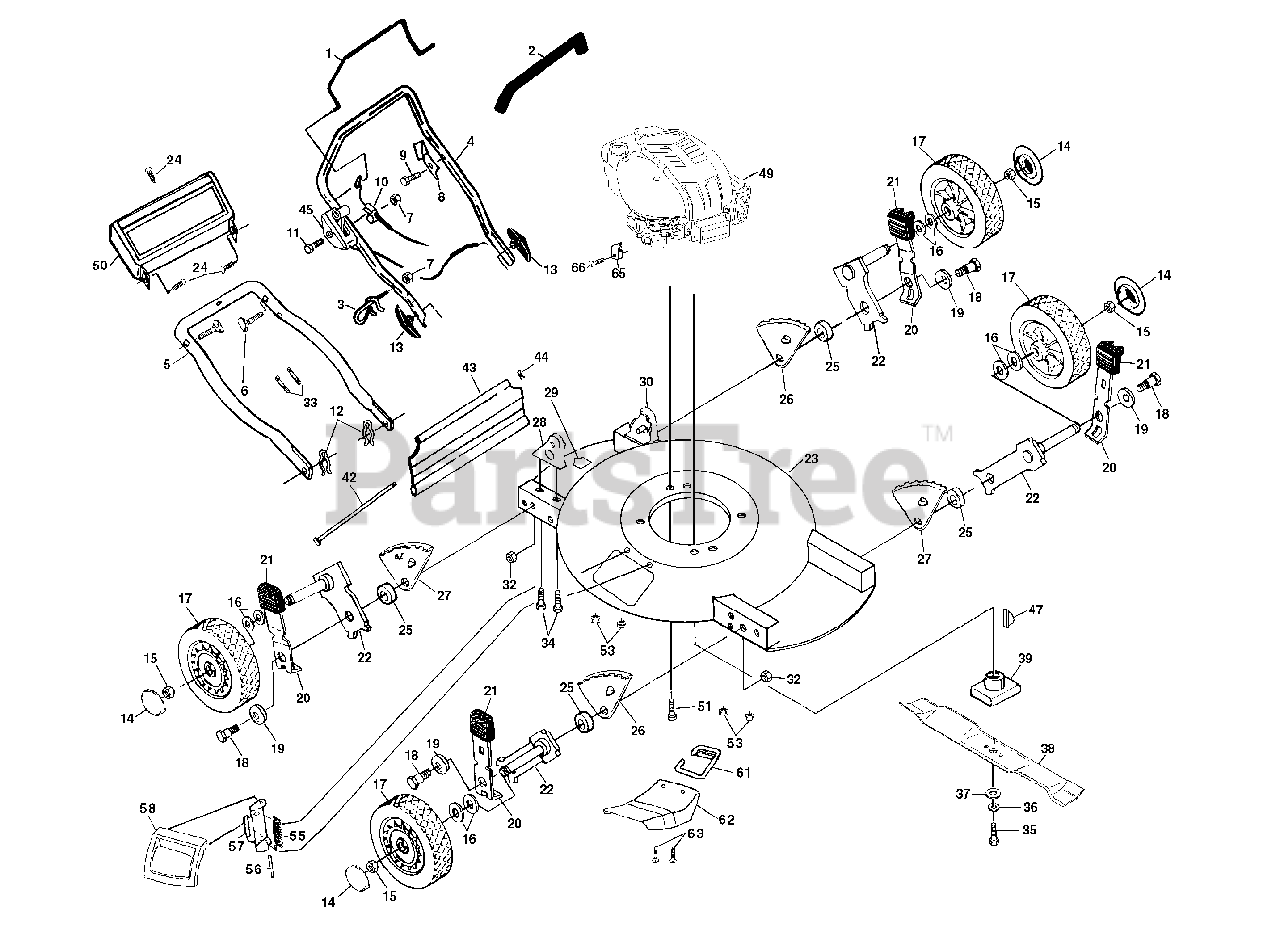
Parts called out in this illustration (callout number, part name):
1	Control Bar
2	Handle Grip
3	Rope Guide
4	Upper Handle
5	Lower Handle
6	Handle Bolt 5/ 16- 18 x 1- 3/4
7	Locknut 1/4 - 20
8	Up - Stop Bracket
9	Hex Washer Head Screw #10-24 x 1/2
10	Engine Zone Control Cable
11	Hex Washer Head Screw 1/4 - 20 x 2.12
12	Hairpin Cotter
13	Handle Knob
15	Hex Locknut 3/8 - 16
16	Washer
17	Wheel & Tire Assembly
18	Shoulder Bolt
19	Belleville Washer
20	Selector Spring
21	Selector Knob
22	Axle Arm Assembly
23	Lawn Mower Housing
24	Push- in Fastener
25	Spacer
26	Wheel Adjusting Bracket (R.F./ L.R.)
27	Wheel Adjusting Bracket (L.F./ R.R.)
28	Handle Bracket Assembly (Right)
29	Danger Decal
30	Handle Bracket Assembly (Left)
32	Locknut 3/8 - 16
33	Wire Ties
34	Thread Cutting Screw 5/16 - 18 x 3/4
35	Hex Head Screw 3/8 - 24 x 1-3/8
36	Helical Lockwasher 3/8
37	Hardened Washer
39	Blade Adapter
42	Deflector Rod
43	Rear Deflector
44	Retainer Clip
45	Throttle Control
49	Engine
50	Trim Plate
51	Hex Head Screw, Self Tap. 3/8 - 16 x 1.1
53	Locknut
55	Torsion Spring
57	Housing Assembly Bracket
58	Mulcher Door
61	Chute Mounting Bracket
62	Mulcher Deflector
63	Truss Head Screw
65	Cable Clamp
